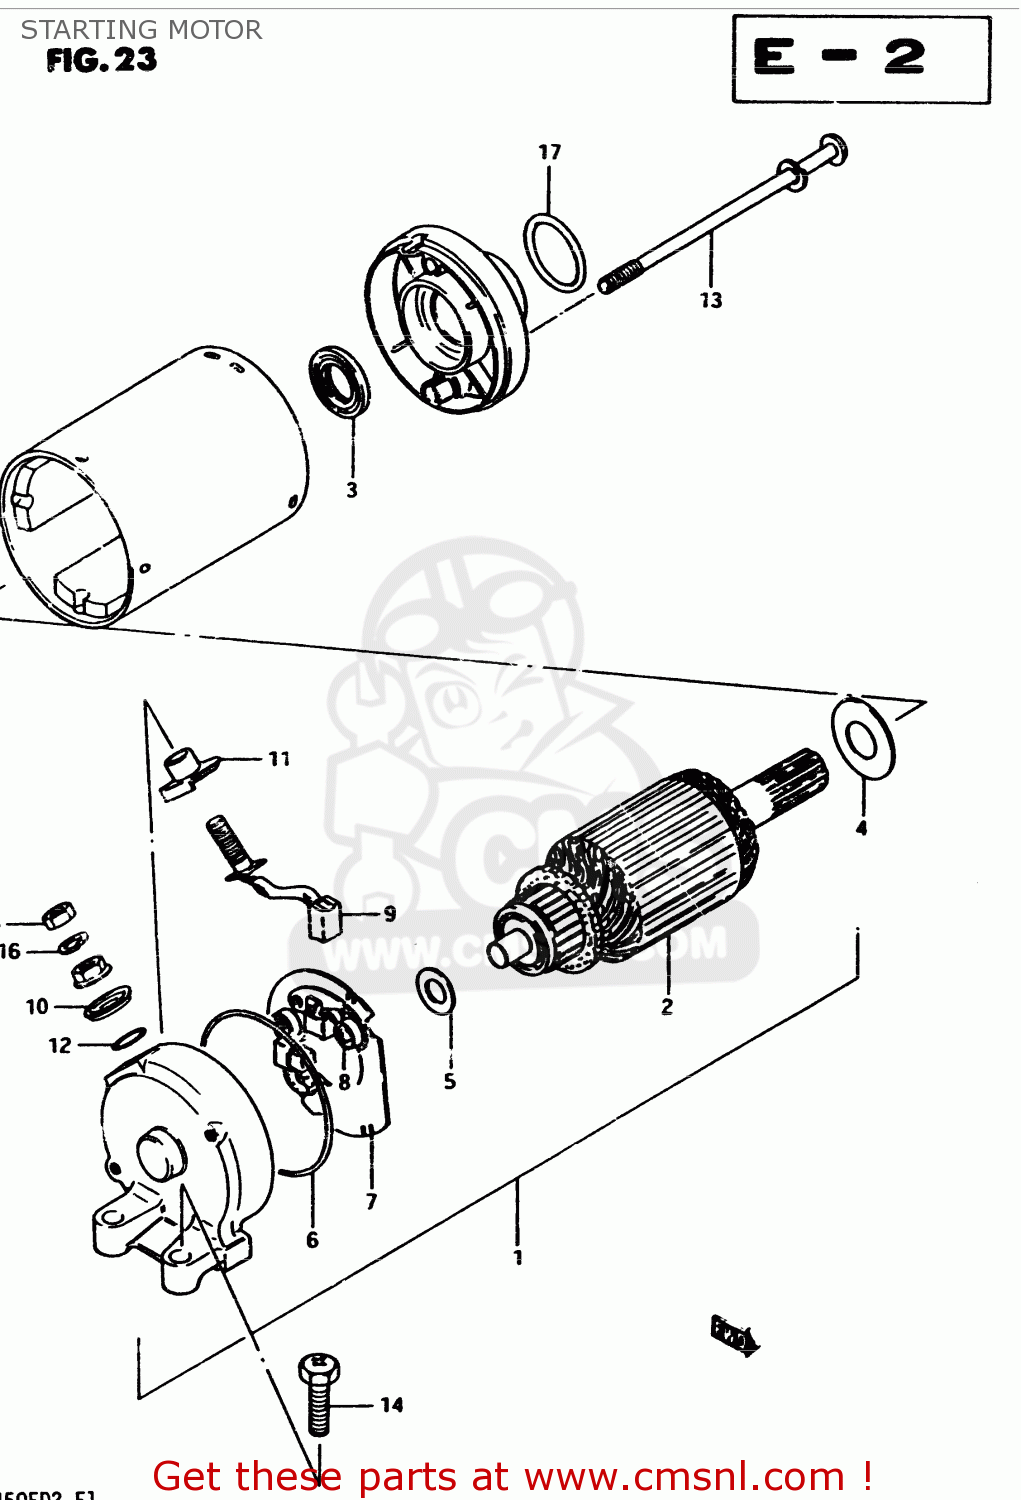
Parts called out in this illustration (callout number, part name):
1	MOTOR ASSEMBLY,STARTING
2	ARMATURE
3	SEAL,OIL
4	RING,SNAP
5	SHIM,ARMATURE
6	O RING
7	HOLDER,BRUSH
8	SPRING
9	BRUSH (+)
10	BUSHING (1)
11	BUSH,NO.2
12	O-RING
13	BOLT,STARTING MOTOR HOUSING
14	SCREW (6X25)
15	NUT
16	LOCK WASHER
17	O RING(D:3,ID:24.5)
